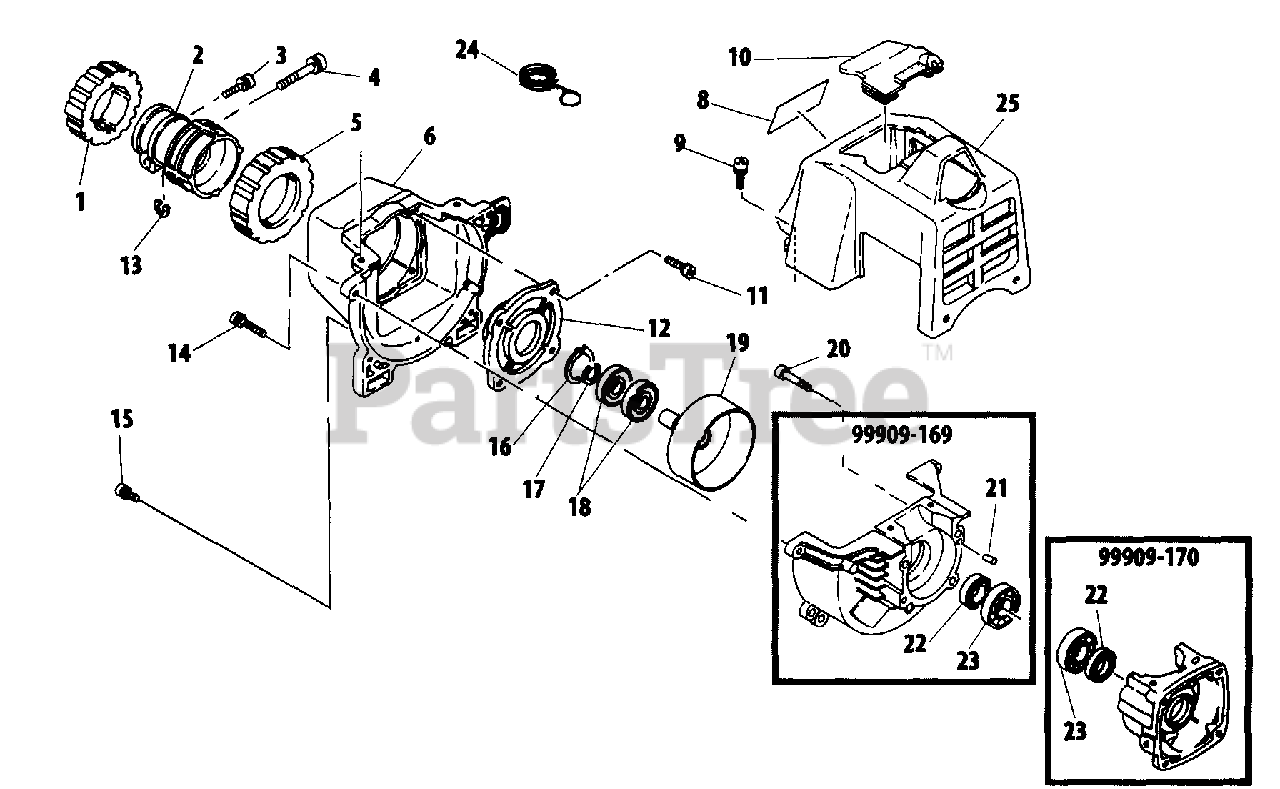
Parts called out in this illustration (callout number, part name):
1	HOLDER, FRONT CUSHION
2	JOINT
4	BOLT M6×28
5	HOLDER, REAR CUSHION
6	CASE, FAN
8	LABEL, TRADE - PB270
9	BOLT M5×16
10	COVER
11	BOLT M5×16
12	CASE, CLUTCH
13	SHIM
14	BOLT M5×18
15	BOLT M5×20
16	RING, SNAP Ø28
17	RING, SNAP Ø12
18	BEARING, BALL 6001 DDU C3
19	DRUM, CLUTCH
20	BOLT 5×25
21	PIN, LOCATING
22	SEAL, OIL 12
23	BEARING, BALL
24	HOLDER, THROTTLE CABLE
25	COVER, ENGINE
